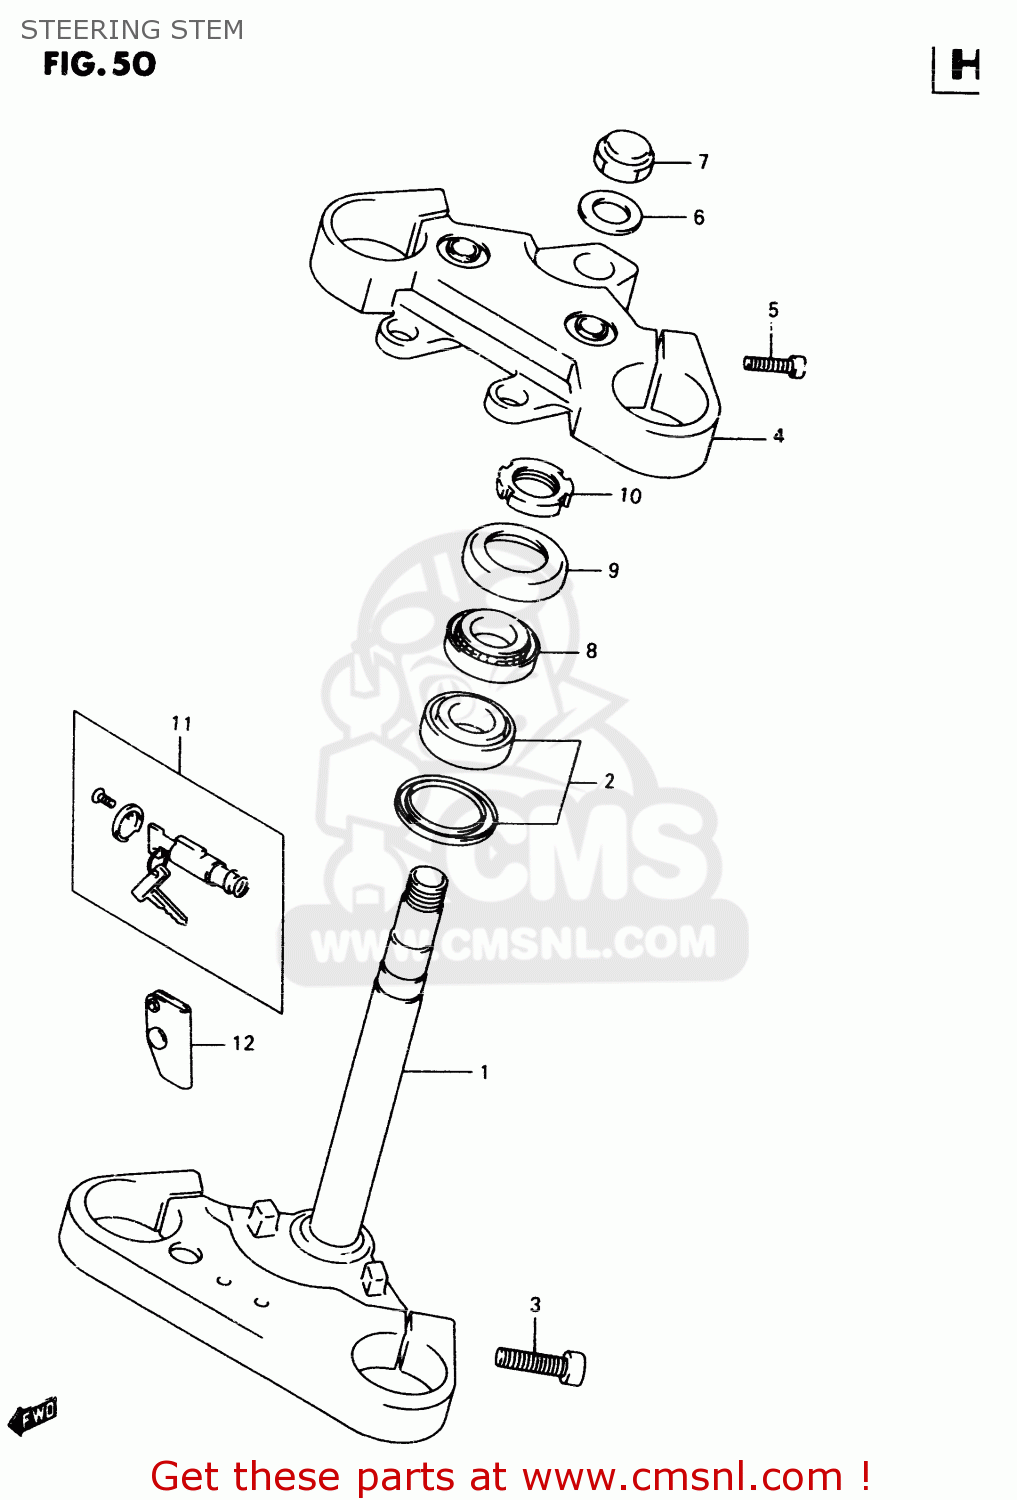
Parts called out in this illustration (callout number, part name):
1	STEM,STEERING
2	BEARING(30X55X17)
3	BOLT,STEM
4	HEAD,STEERING STEM
5	BOLT,STEM HEAD
6	WASHER(22.5X35.9X1.6)
7	NUT,CAP
8	BEARING(25X47X15)
9	SEAL,STEERING UPR DUST
10	NUT,STEERING STEM(25X44X10)
11	LOCK SET,STEERING
12	CASE,STEERING KEY
